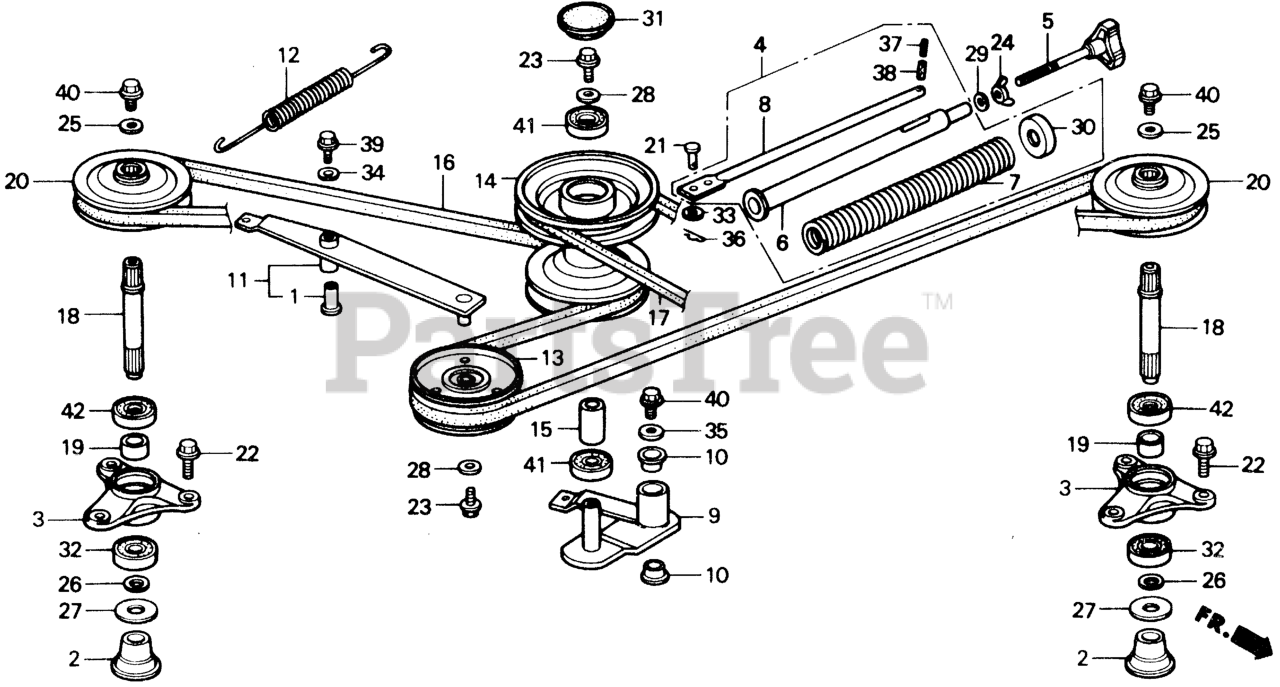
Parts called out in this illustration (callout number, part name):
1	BUSH (15X19X39.5)
2	HOLDER, BLADE
3	HOUSING, BEARING
4	PIPE ASSY., TENSIONER
5	KNOB, TENSIONER SPRING RELEASE
6	PIPE, SPRING SETTING
7	SPRING, TENSIONER LOAD SETTING
8	SHAFT, SPRING SET
9	ARM, TENSION
10	BUSH, TENSIONER ARM
11	ARM, TENSIONER (DECK)
12	SPRING, TENSIONER ARM B
13	ROLLER, TENSIONER
14	PULLEY, DRIVEN
15	COLLAR, DRIVEN PULLEY
16	V-BELT, BLADE (LB-73)
17	V-BELT, DRIVE (LB-104)
18	SHAFT, BLADE
19	COLLAR, BLADE SHAFT
20	PULLEY, BLADE (115MM)
21	PIN, TENSIONER ARM (10X19.5)
22	BOLT, FLANGE (10X28)
23	BOLT, WHEEL
24	WINGNUT (8MM)
25	WASHER (10.5X27X4)
26	WASHER, THRUST (20MM)
27	WASHER, BLADE HOLDER
28	WASHER (8MM)
29	WASHER, TENSIONER SPRING RELEASE (8.3X23X3.2)
30	WASHER, BRAKE SPRING SETTING
31	PLUG, SEALING (40X8)
32	BEARING, RADIAL BALL
33	WASHER, PLAIN (10MM)
34	WASHER, PLAIN (8MM)
35	WASHER, PLAIN (10MM)
36	PIN, LOCK (10MM) Use from Frame SN 2149606 to 2149605.
37	PIN, SPRING (3X28)
38	PIN, SPRING (5X28)
39	BOLT, FLANGE (8X12)
40	BOLT, FLANGE (10X16)
41	BEARING, RADIAL BALL (6203UU)
42	BEARING, RADIAL BALL (6204UU)
